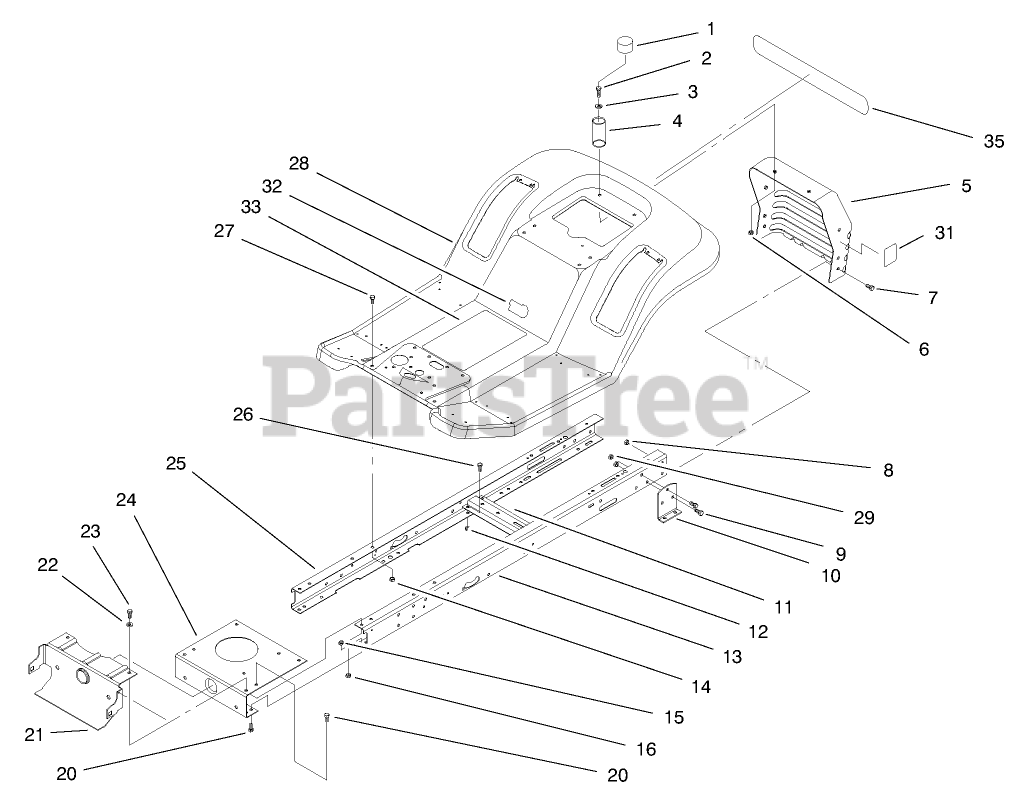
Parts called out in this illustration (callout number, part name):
1	CAP-PROTECTOR
2	SCREW-HH
3	WASHER-PLAIN
4	SPRING-COMPRESSION
6	NUT-LOCK, NI
7	SCREW-HH
8	NUT-LOCK, NI
9	SCREW-HH
10	BRACKET-TRANSAXLE, MOUNTING
11	BRACKET-IDLER PIVOT
12	NUT-LOCK, NI
14	NUT-LOCK, NI
15	NUT-LOCK, NI
16	NUT-LOCK, NI
20	SCREW-HH
22	WASHER-PLAIN
23	SCREW-HH
24	PLATE-MOUNTING, ENGINE
26	SCREW-HH
27	SCREW-HH
29	NUT-LOCK, NI
32	DECAL - USA
33	DECAL - INSTRUCTION HYDRO
35	DECAL-REAR, BODY
